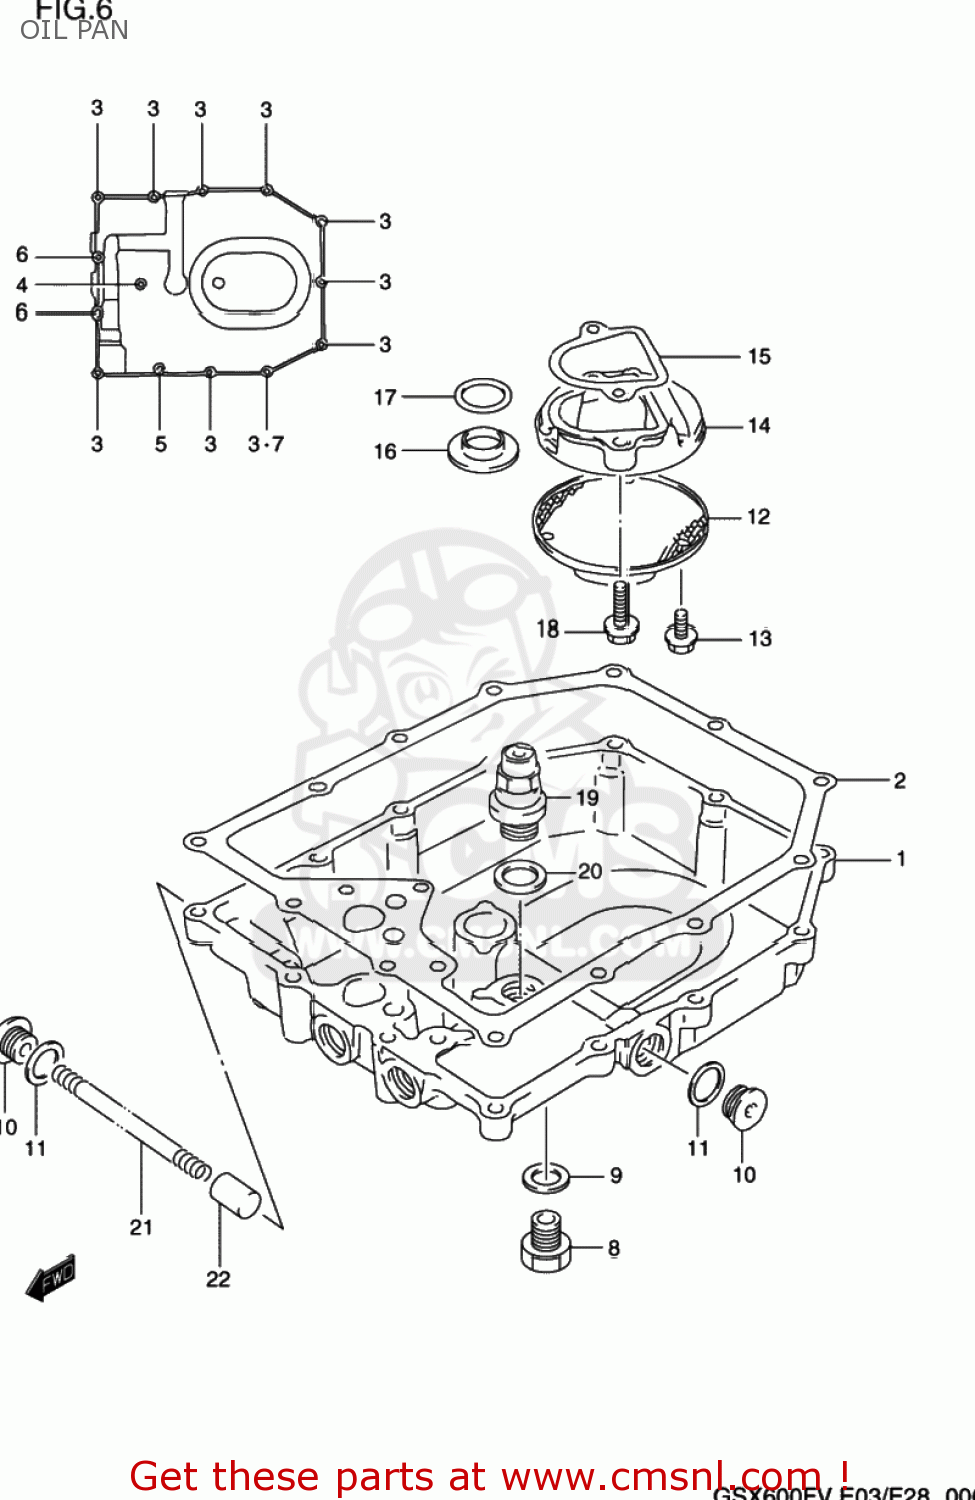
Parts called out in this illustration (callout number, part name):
1	PAN,OIL
2	GASKET,OIL PAN (NAS)
3	BOLT,CL.COVER
4	BOLT
5	BOLT
6	BOLT
7	GASKET(5.8X11X1.2) (NAS)
8	PLUG
9	GASKET(13.8X18.8X4.8) (NAS)
10	PLUG
11	GASKET(16X22X2) (NAS)
12	STRAINER,ENGINE OIL
13	BOLT
14	PROTECTOR,OIL STRAINER
15	GASKET,OIL STRAINER PROTECTOR (NAS)
16	GASKET,OIL OUTLET (NAS)
17	O RING(D:3.2,ID:17.8)
18	BOLT
19	VALVE ASSY,OIL RELIEF
20	GASKET(16X22X2) (NAS)
21	SPRING
22	PLUNGER,OIL CONTROLL
